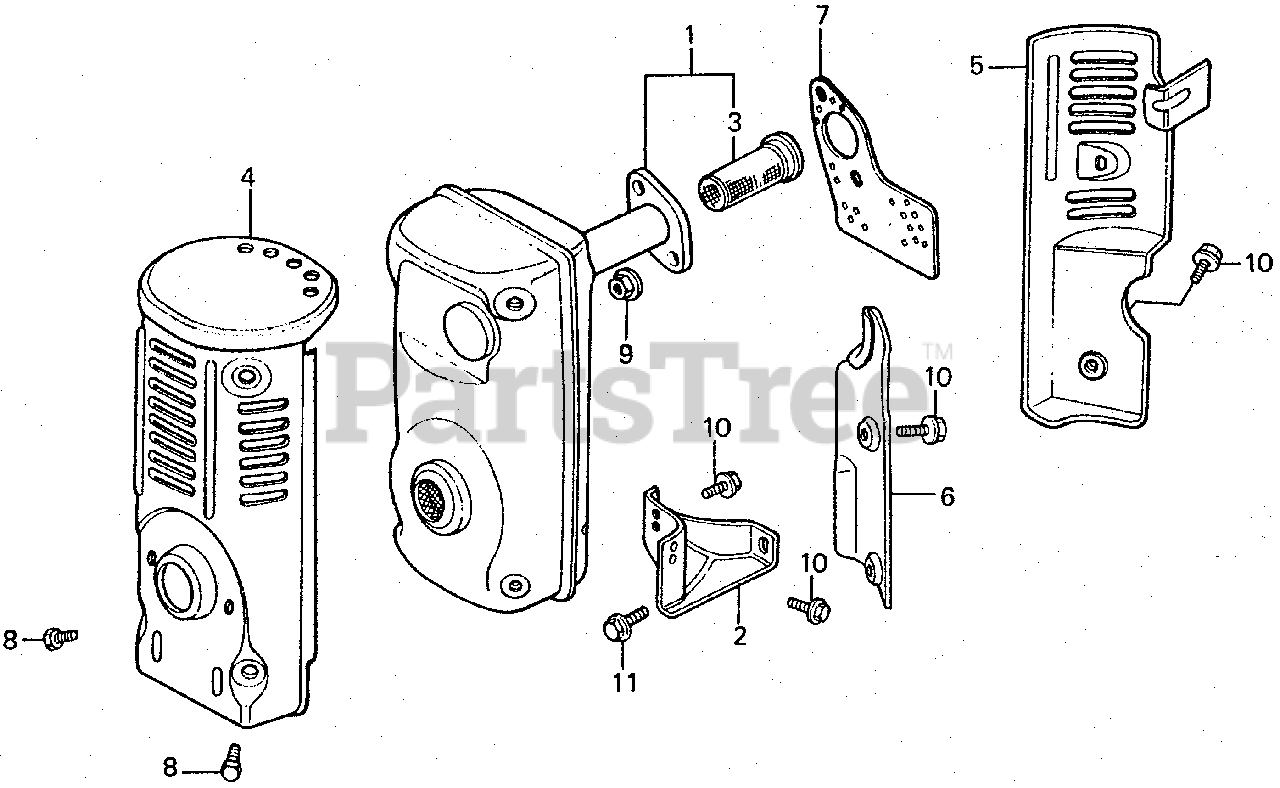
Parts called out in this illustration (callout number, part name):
1	MUFFLER
1	MUFFLER (NOT AVAILABLE)
2	STAY, MUFFLER
3	ARRESTER, SPARK
4	PROTECTOR A, MUFFLER
5	PROTECTOR B, MUFFLER
6	PROTECTOR C, MUFFLER
7	GASKET, MUFFLER
8	BOLT-WASHER (6X10)
8	BOLT, HEX. (6X8)
9	NUT, FLANGE (8MM)
10	BOLT, FLANGE (6X10)
11	BOLT, FLANGE (8X14)
11	BOLT, FLANGE (8X16)
